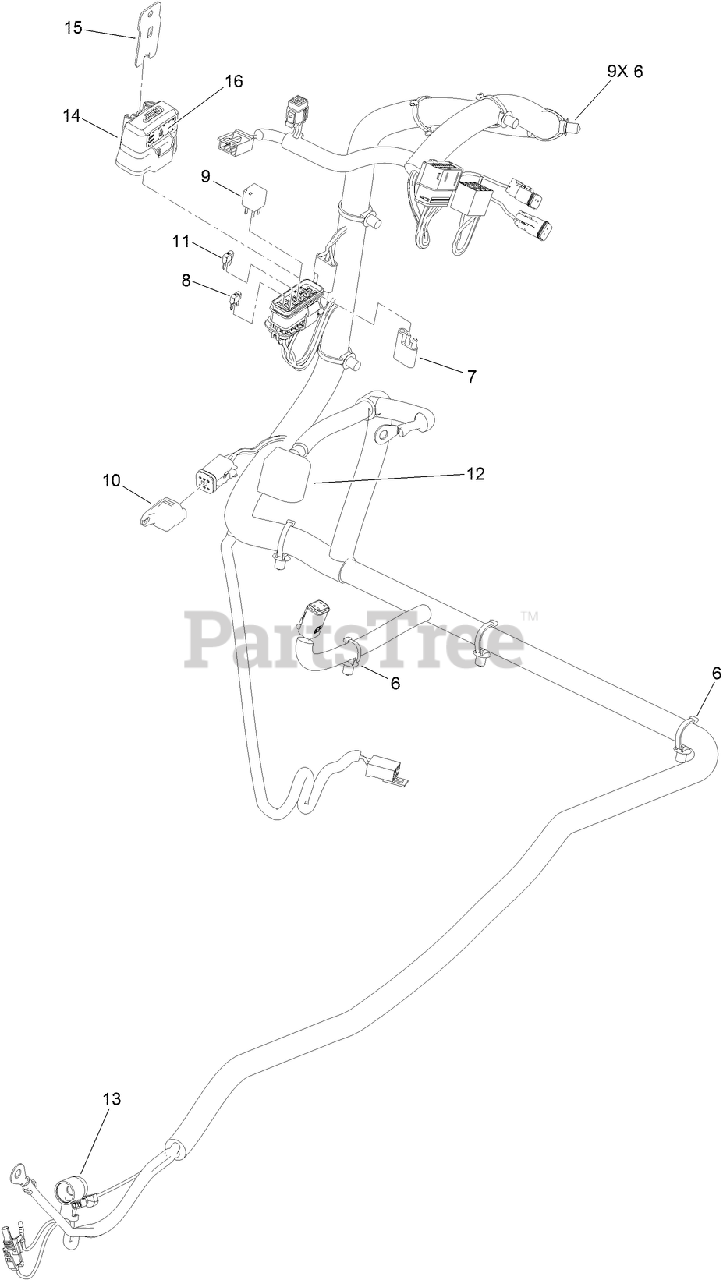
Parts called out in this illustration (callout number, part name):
6	CLIP-TIE
7	CAP-PLUG
8	FUSE-MINI BLADE, 20 AMP
9	RELAY-MICRO
10	CAP-PLUG, 6 WAY
11	FUSE-MINI BLADE, 15 AMP
12	INSULATOR-BATTERY
13	INSULATOR-SOLENOID
14	COVER-BLOCK, FUSE
15	CLIP-MOUNTING
16	DECAL-FUSE
